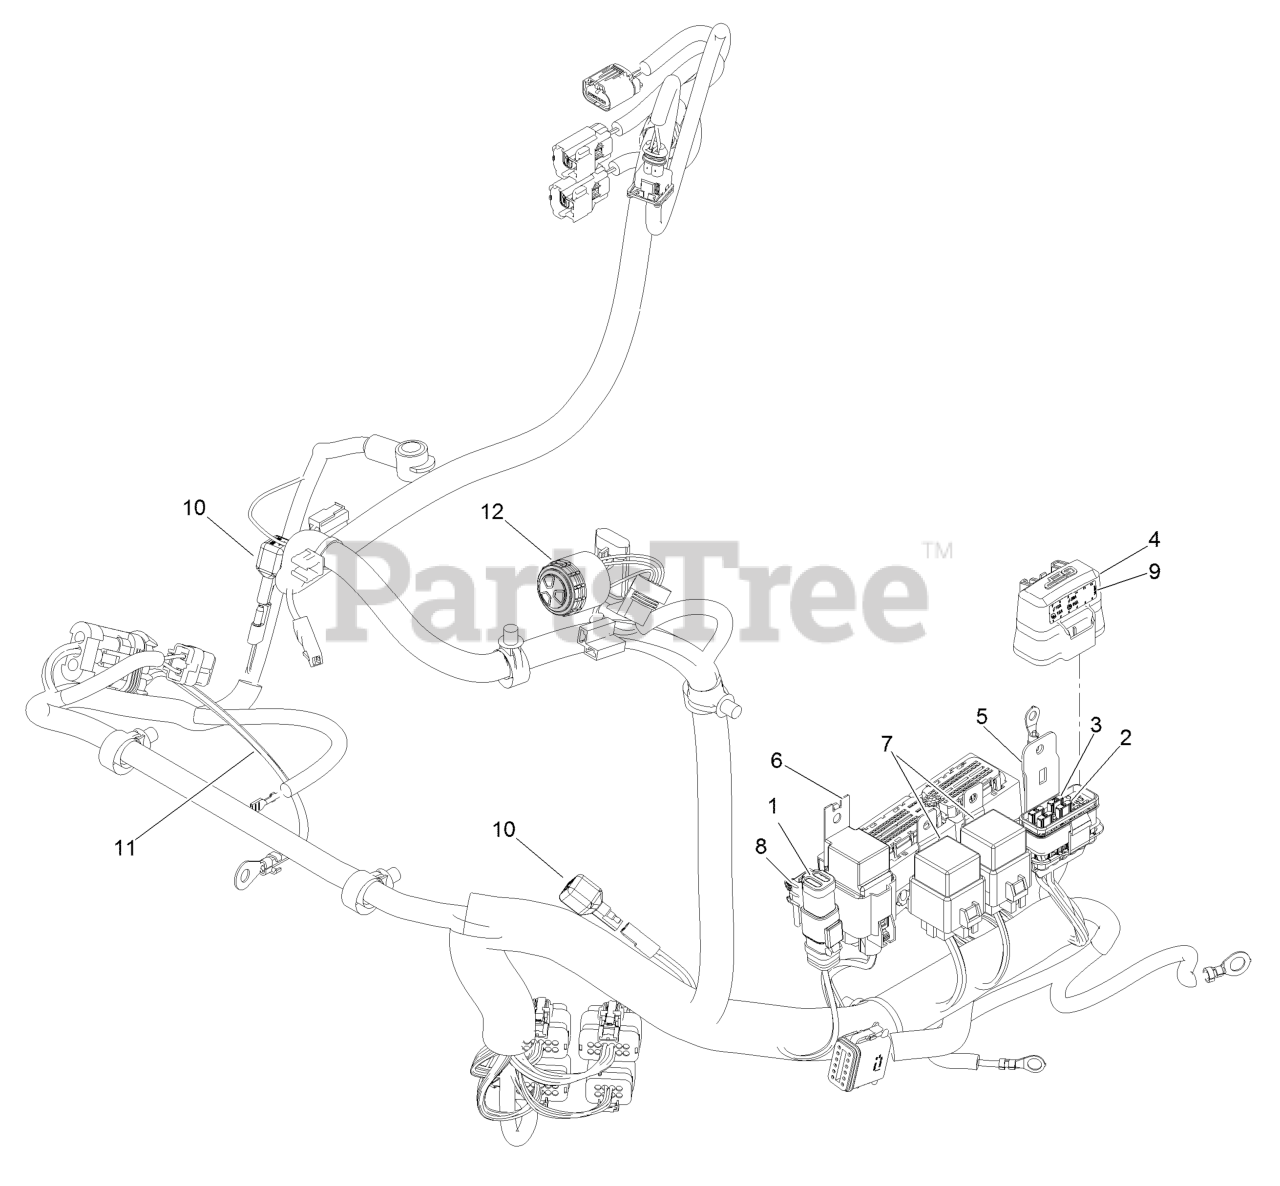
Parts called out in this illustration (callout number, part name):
1	Connector (6M)
2	Fuse-Mini Blade, 15 Amp
3	Fuse-Mini Blade, 25 Amp
4	Cover-Block, Fuse
5	Clip-Mounting
6	Relay-70A
8	Clip-Connector
9	Decal-Fuse
11	Harness-Wire, Fusible Link
12	Alarm-Dual Tone
